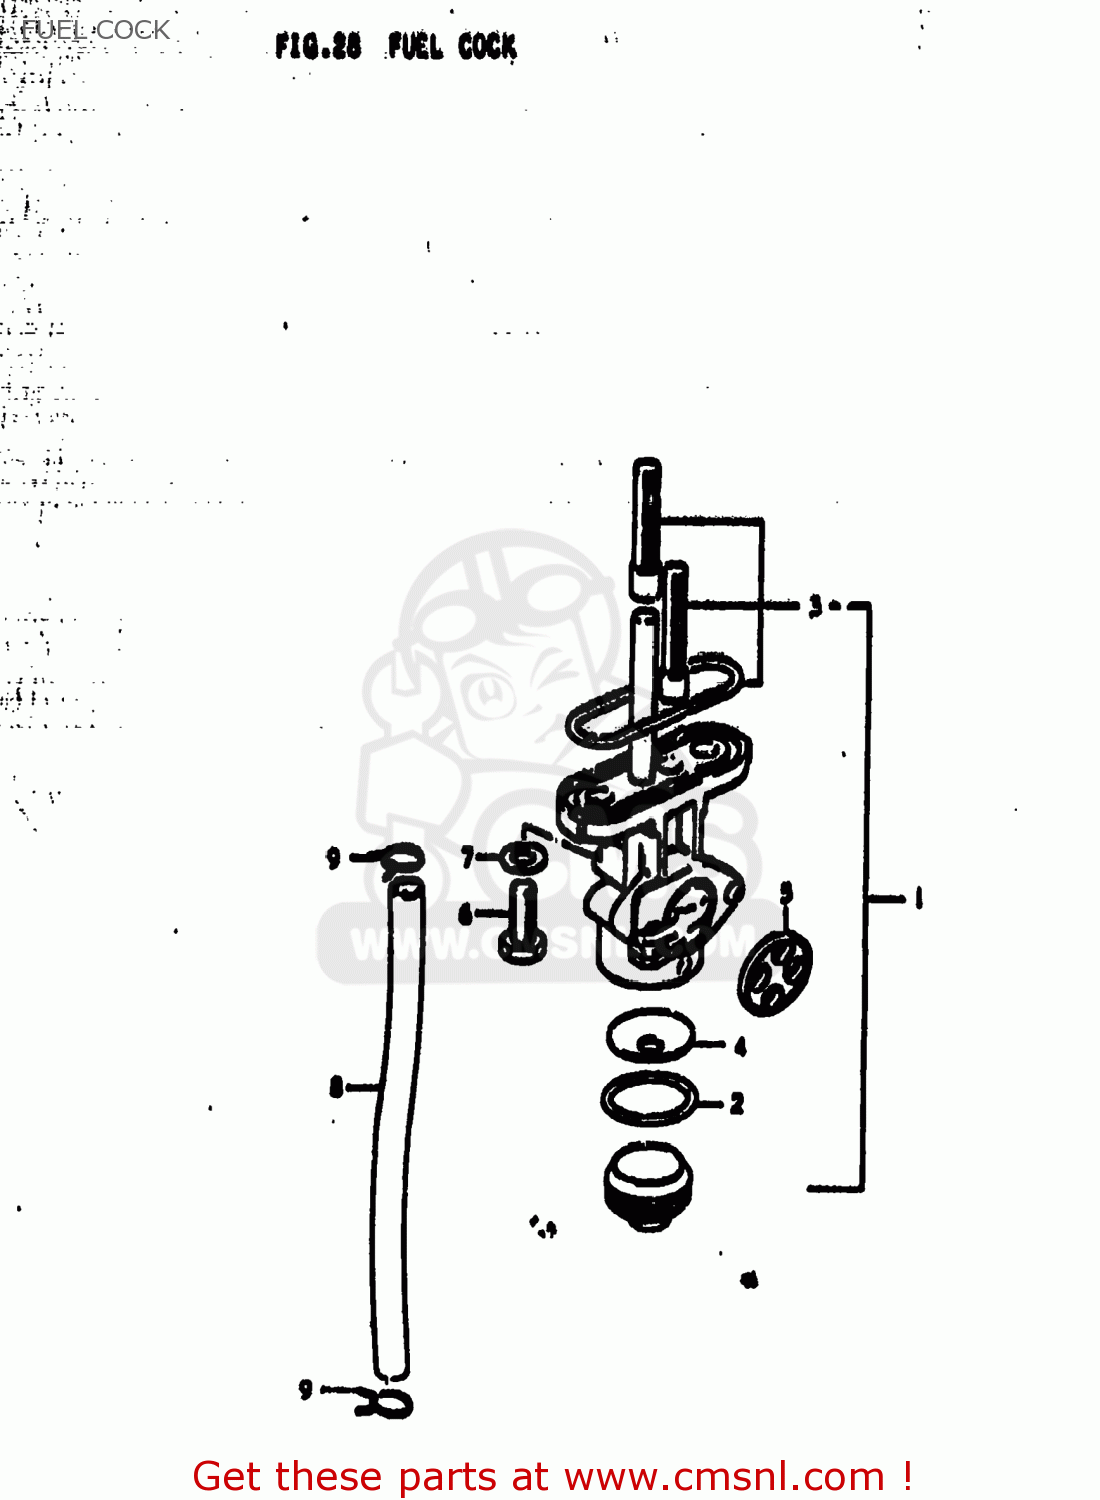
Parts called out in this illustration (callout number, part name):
1	COCK ASSEMBLY,FUEL
2	GASKET,FILTER (NAS)
3	FILTER SET,FUEL COCK
4	NET,STRAINER
5	GASKET,LEVER (NAS)
6	BOLT L:16
7	GASKET
8	HOSE
9	CLIP
